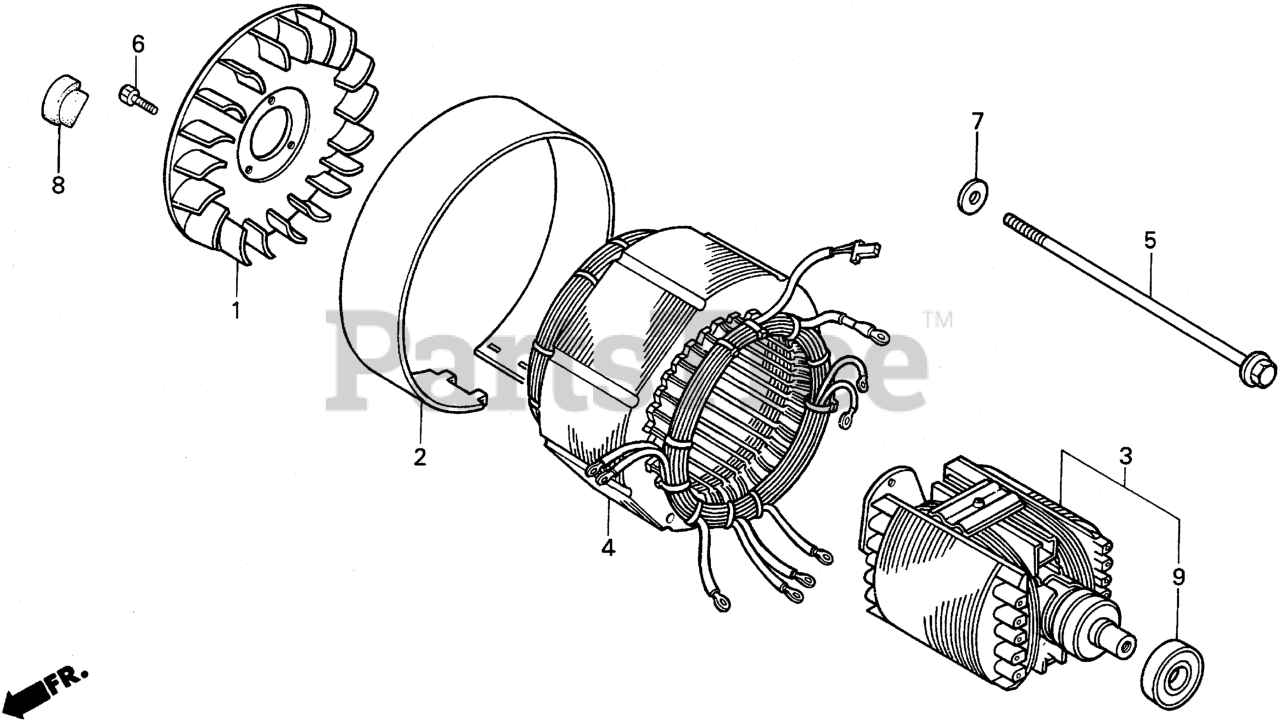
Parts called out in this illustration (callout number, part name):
1	FAN, GENERATOR COOLING
2	COVER, STATOR
3	ROTOR
4	STATOR ASSY.
5	BOLT, HEX. (10X243)
6	SCREW, TAPPING (5X14)
7	WASHER (10.5MM)
8	GROMMET, CRANKCASE
9	BEARING ASSY. (6205)
9	BEARING, RADIAL BALL (6205UU)
